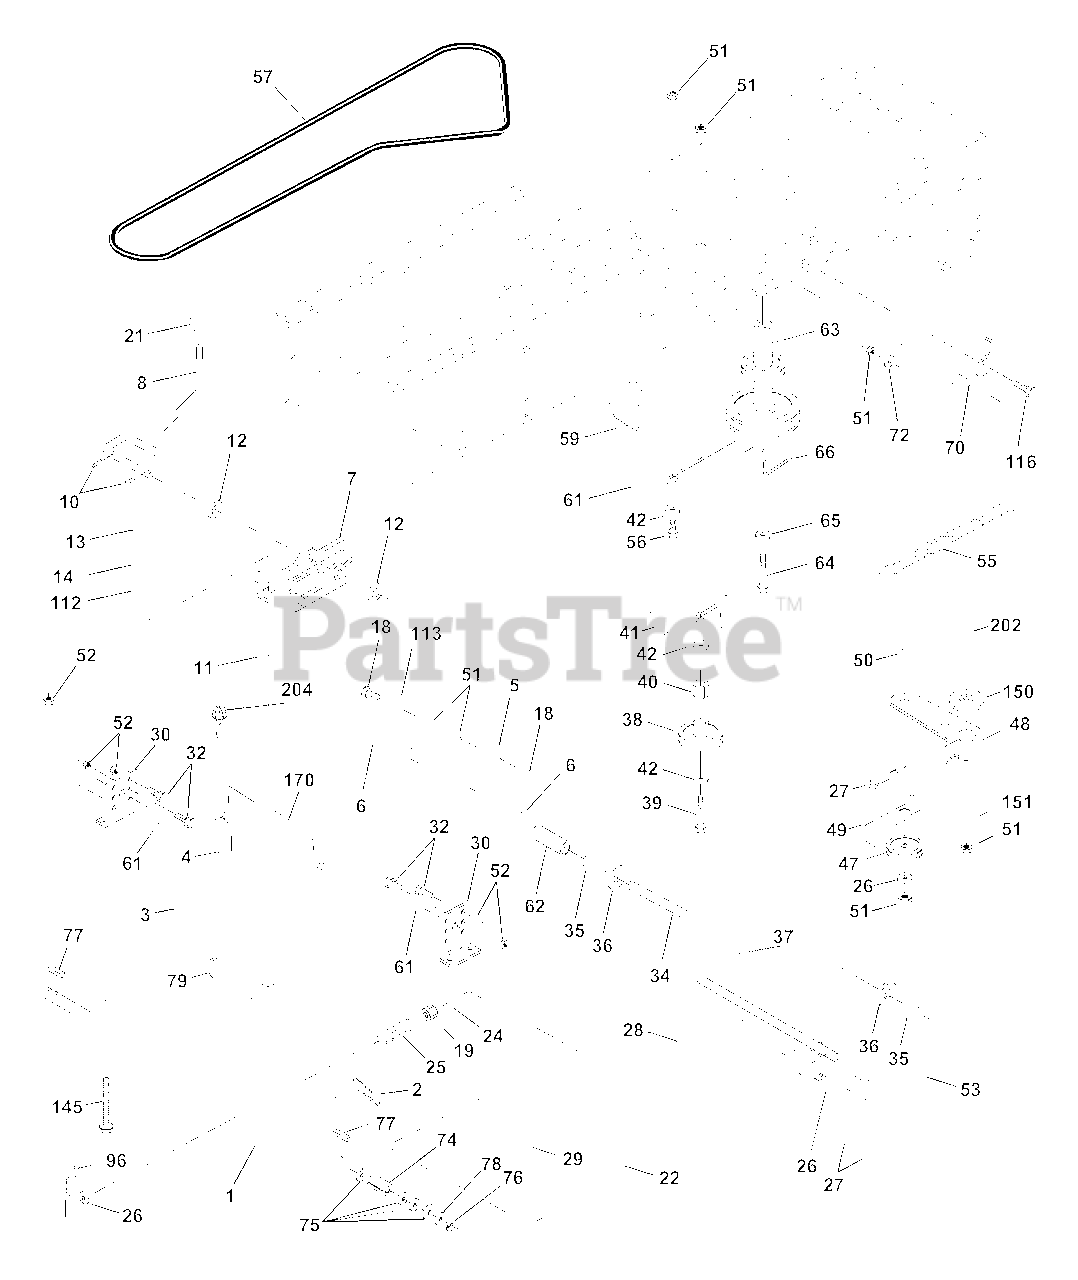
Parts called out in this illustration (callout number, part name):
2	Spring Return Brake
3	Pulley Transaxle 18"tires
4	Ring Retainer # 5100-62
5	Strap Torque 30 Degrees RH
6	Screw 5/16-18 x 3/4
7	Plate Rod Shift T/a
8	Rod Shifter Blk
10	Pin Cotter 1/8 X 1 Cad
11	Washer Plate Shf 388 Sq Hole
12	Washer 15/32 X 3/4 X 16 Ga
13	Bolt 1/4-28 unf Gr. 8 w/Patch
14	Washer Lock Hvy Helical 1/4
18	Bolt Fin Hex 3/8-16unc X 1 Gr. 5
19	Nut lock Hex w/Ins 3/8-16 Unc
21	Knob Rd 1/2-13 Plstc Thds Blk
22	Rod Brake LT
24	Nut Hex Jam 3/8-16 Unc
25	Spring Rod Brake 2 00 Zinc
26	Washer 13/32 X 13/16 X 16 Ga
27	Pin Cotter 1/8 X 3/4 Cad
28	Rod Brake Parking LT/YT
29	Cap Brake Parking Black
30	Bracket Transmission
32	Bolt Fin Hex 5/16-18 x 3/4
34	Shaft Asm Pedal Foot
35	Bearing Nylon Blk 629 Id
36	Washer 21/32 X 1 X 16 Ga
37	Pin Roll 3/16 X 1"
38	Pulley Idler Flat
39	Bolt Rdhd 3/8-16 Unc x 2-3/4 Gr.5
40	Spacer Split 395 X 59 Bzp
41	Keeper Belt Idler
42	Washer 13/32 X 13/16 X 12 Ga
47	Pulley Idler V Groove Plastic
48	Bellcrank Clutch Grnd Drv STL
49	Retainer Belt Style Spring
50	Bolt Hex Hd 3/8-16unc X 1-1/2
51	Nut Crownlock 3/8-16 Unc
52	Nut Crownlock 5/16-18 unc
53	Link Clutch 7 66
55	Spring Return Clutch 6 75
56	Bolt Fin Hex 3/8 X 16 x 1-1/4
57	V-Belt Ground Drive 95
59	Keeper Belt Chassis Span Ctr
61	Screw 3/8-16 x 3/4
62	Cover Pedal Blk Round
63	Engine Pulley LT/YT
64	Bolt Hex 7/16-20x4 Gr 5
65	Washer Lock Hvy Hlcl Spr 7/16
66	Keeper Belt Engine
70	Guide Belt Mower Drive RH
72	Washer 13/32 X 1-1/4 X 12 Ga
74	Spacer Axle
75	Washer 25/32 X 1 1/4 X 16 Ga
76	E-ring #5133-75
77	Key Square 2 0 X 1845/ 1865
78	Washer 25/32 X 1-5/8 X 16 Ga
79	Key Woodruff
96	Retainer Spring 1"
112	Washer 9/32 X 3/4 X 10 Ga
113	Strap Torque 90 Degrees LH
116	Bolt Rdhd Sq Neck 3/8-16 x 1.25
145	Bolt Hex Flg.Hd. 5/16-18 x Gr.5
150	Bushing Bellcrank
151	Washer 13/32 x 2 x 10 Ga.
170	Keeper, Belt Transaxle Gear
202	Bolt Carr Sh 3/8-16 x 1-1/2 Gr.5
204	Screw 5/16-18 x 1
